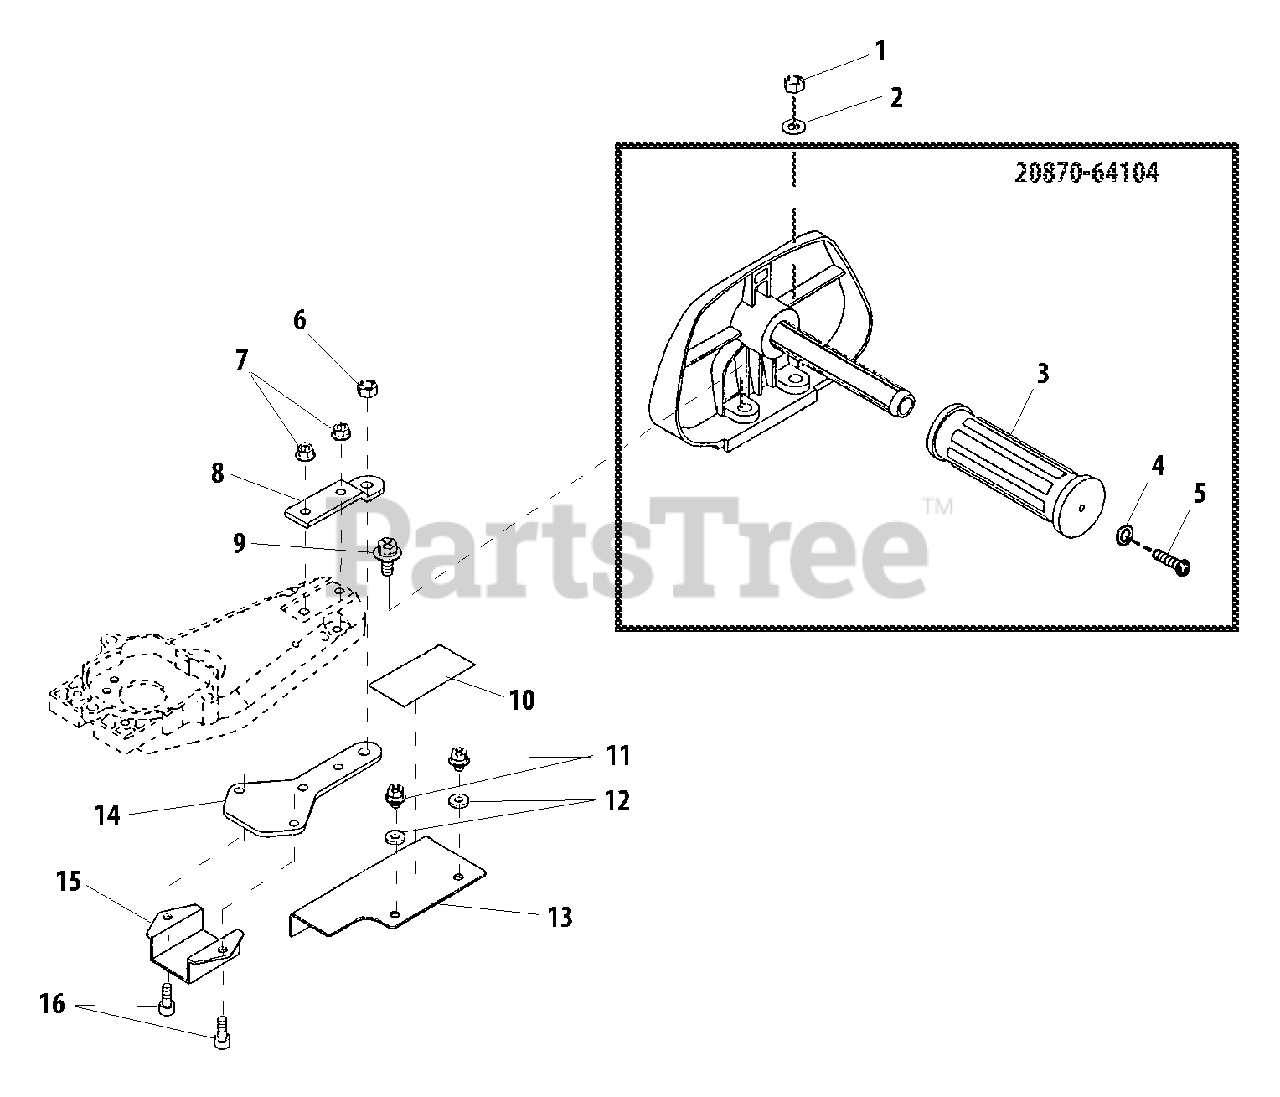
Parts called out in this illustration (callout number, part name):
1	NUT - 6
2	WASHER - 6
3	GRIP
4	WASHER - 5
5	SCREW - 5X20
6	NUT - 6
7	NUT - 5 -- FLANGE
8	HOLDER
9	NUT - 5 -- FLANGE
10	LABEL - WARNING
11	BOLT - 5X8
12	WASHER - VYNYL
13	PROTECTOR
14	PLATE
15	BRACKET
16	SCREW - 5X12
20870-64104	HANDLE ASSY - FRONT
